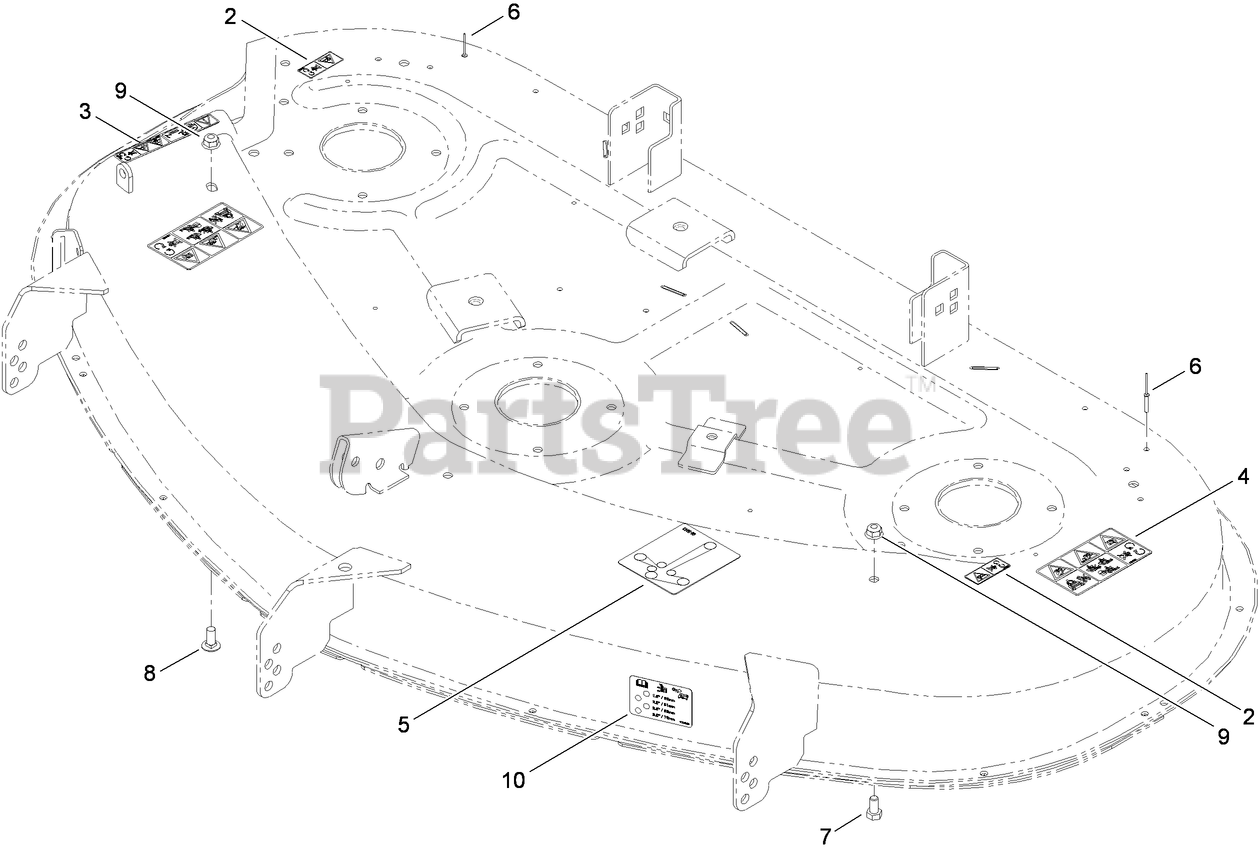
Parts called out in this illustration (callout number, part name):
2	DECAL-DANGER
3	DECAL-DANGER
4	DECAL-DANGER
5	DECAL-ROUTING, BELT
6	RIVET-BLIND
7	SCREW-HH
8	SCREW-CARR
9	NUT-HF, NI
10	DECAL-SCALP, ANTI
